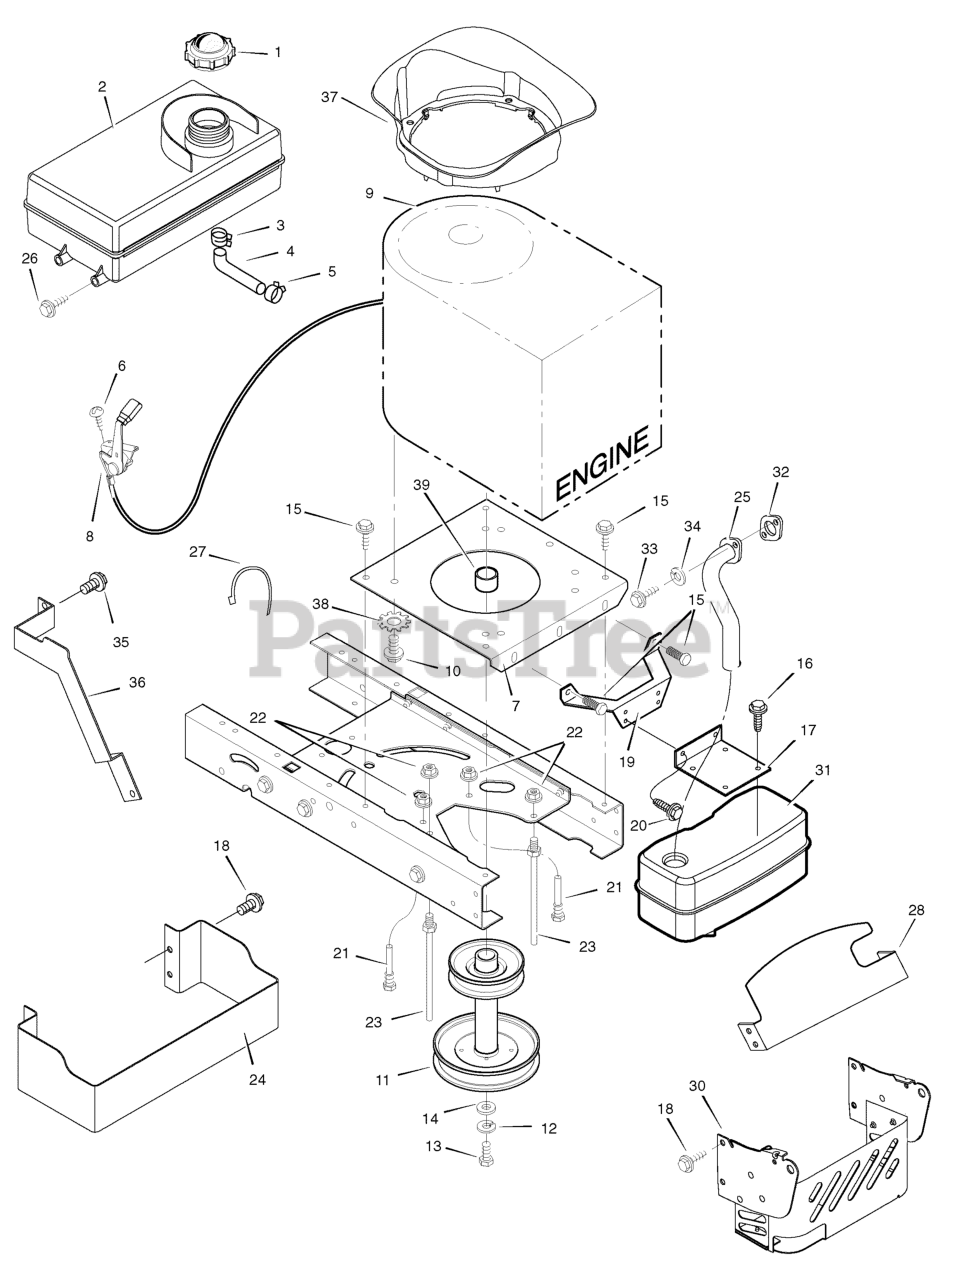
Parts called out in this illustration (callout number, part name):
1	FUEL CAP
2	TANK, Fuel 1.4 Gal.
3	CLAMP, Hose
4	FUEL LINE (Must cut to length)
5	CLAMP, Hose
7	PLATE, Engine
8	THROTTLE CONTROL
9	ENGINE, Briggs & Stratton *
10	BOLT, Engine Mount
11	STACK PULLEY ASSEMBLY
12	LOCKWASHER
13	BOLT, Hex
17	BRACKET, Muffler
19	BRACKET, Muffler Mount
21	GUIDE, Belt
22	NUT, Flange
23	GUIDE, Belt
24	GUARD, Heat Shield
25	EXHAUST TUBE, Single
27	TIE, Strap, 5.38 Long
28	GUARD, Heat Shield, Upper
30	SHIELD, Heat
31	MUFFLER
32	GASKET, Exhaust
34	WASHER
35	BOLT, Washer Hex Head
36	GUARD, Exhaust Pipe
37	PLENUM, X1 M28/31
38	WASHER, Star .38 0.68X
39	SPACER, Engine
